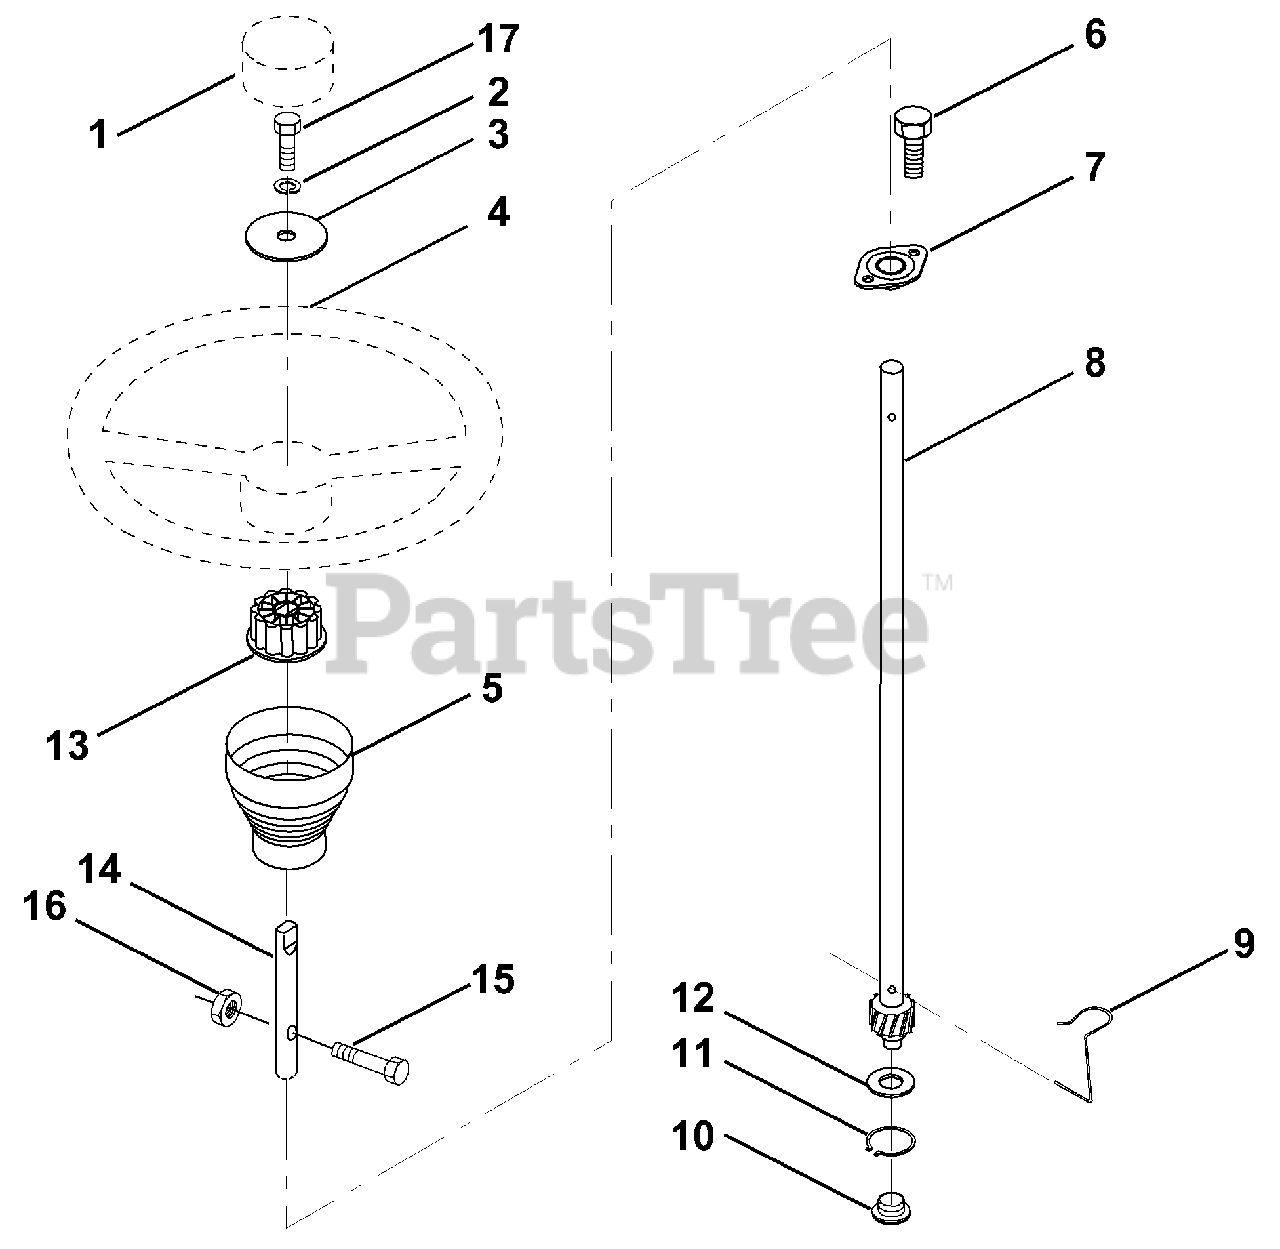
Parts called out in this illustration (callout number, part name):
1	Insert, Wheel, Steering
2	Washer, Lock hvy HLCL SPR 3/8
3	Washer 12/32 x 2-3/8 x 8 Ga.
4	Wheel, Steering
5	Sleeve, Steering
6	Screw, TT #10-32.5.3/8 flange
7	Bushing, Steering
8	Shaft, Steering
9	Clip, Steering
10	Bushing, Lower, Steering
11	Ring, Retaining
12	Washer 21/32 x 1 x 16 Ga.
13	Adaptor, Wheel, Steering
14	Extension shaft steering
15	Bolt Fin Hex 5/16-18 UNC x 1-1/4
16	Nut Lock Hex W/Ins. 5/16-18 UNC
17	Bolt fin Hex 3/8-16 UNC x 1. Gr. 5
